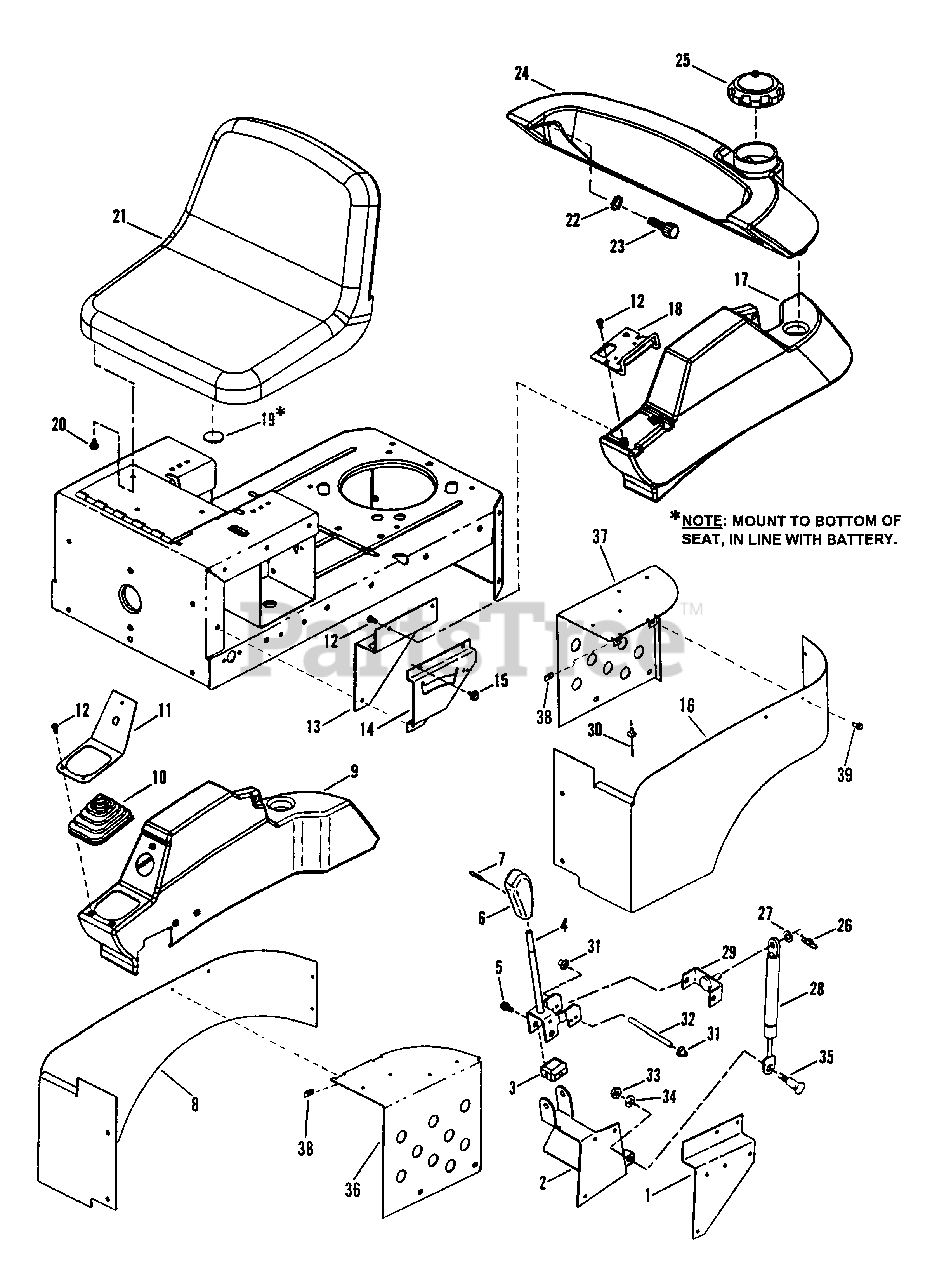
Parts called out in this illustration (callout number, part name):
1	BRACKET, Right Hand Tank Support
2	BRACKET, Joystick
3	PIVOT, Joystick Control
4	HANDLE, Joystick Control
5	BOLT, 5/16-18 x 3/4" Shoulder
6	LEVER, Shift Handle
7	PIN, 3/16 x 3/4" Roll
8	FENDER, Right Hand Rear Frame
9	FENDER, Upper Right Hand
10	BOOT, Joystick, Rubber
11	BRACKET, Joystick/Key
12	SCREW, 1/4 x 5/8" Pan Head Self-Tapping
13	BRACKET, Left Hand Tank Support
14	BRACKET, Brake/Clutch Detent
15	SCREW, 1/4-20 x 5/8" Self-Tapping
16	FENDER, Left Hand Rear Frame
17	FENDER, Upper Left Hand
18	GUARD, Throttle Control
19	BUMPER, Battery
20	SCREW, 5/16-18 x 1/2" Hex Machine
21	SEAT (All Models)
22	WASHER, 1/4" Internal/External Tooth
23	SCREW, 1/4-20 x 1-1/2" Thumb
24	ASSEMBLY, Fuel Tank
25	CAP, Fuel Tank (w/Gage & Screw Vent)
26	COTTER-PIN, 3/8 Self Locking
27	WASHER, 11/32 x 11/16" Flat
28	CYLINDER, Joystick Control
29	BRACKET, Joystick Control
30	RIVET, 3/16" x 1", Dome Head
31	PUSH-NUT, 1/4"
32	PIN, Joystick
33	NUT, 5/16-18 Hex, Grade 5
34	WASHER, 21/64 Split Lock
35	BOLT, 5/16-18 x 1-1/8" Shoulder
36	SUPPORT, Right Hand Fender
37	SUPPORT, Left Hand Fender
38	U-CLIP, #10-24
39	SCREW, #10-24 x 1/2" Machine
